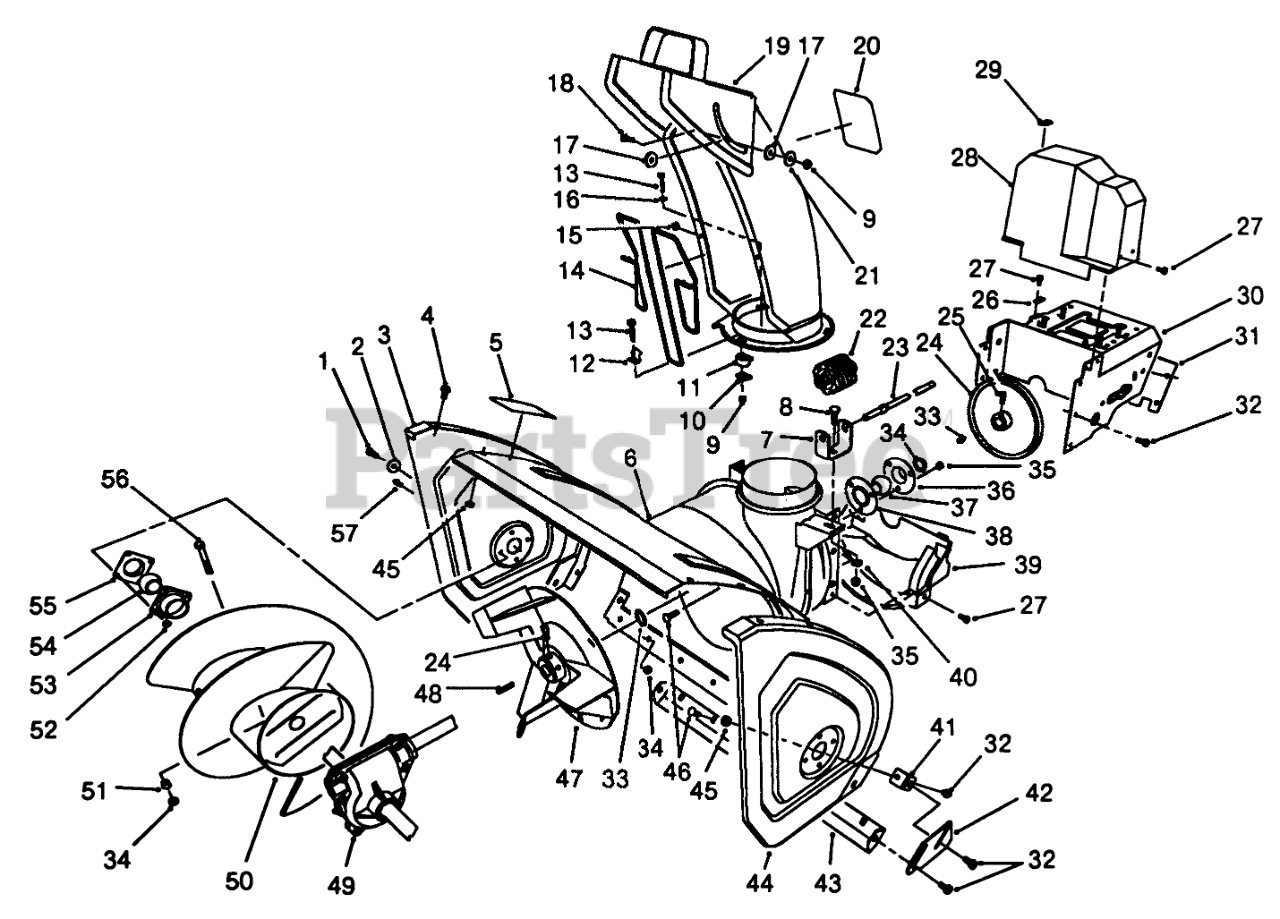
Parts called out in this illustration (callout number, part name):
1	SCREW-HH
2	WASHER
3	R/H SIDEPLATE R
4	SCREW-HHF
5	DECAL-WARNING, AUGER
6	Housing-24 Inch
7	BRACKET-WORM, CHUTE
8	BOLT-CARR
9	NUT-LOCK, NI
10	PLATE-RETAINER, CHUTE
11	RETAINER-CHUTE
12	CLIP-GUARD, CHUTE
13	SCREW-HSH
14	GUARD-CHUTE
15	NUT-PUSH
16	WASHER-FLAT
17	WASHER-PLASTIC
19	Assembly
20	Decal-Danger
21	WASHER-FLAT
22	GEAR-WORM
23	ROD-CHUTE, LOWER
24	PULLEY-IMPELLER
25	SCREW-SET, SQH
26	RETAINER-CABLE
27	SCREW-HWH
28	COVER-BELT, UPPER
29	COVER-CABLE
30	Frame-Engine
31	Cover-Frame, Engine
32	SCREW-HHF
33	KEY-WOODRUFF
34	WASHER-THRUST
35	NUT-LOCK, NI
36	FLANGE-CUP, BEARING
37	BEARING-BALL
38	FLANGE-CUP, BEARING
39	Cover-Belt (Lower)
40	WASHER-PLAIN
41	Bracket-Skid
42	Plate-Skid LH
43	Blade-Scraper
44	L/H SIDEPLATE R
45	NUT-LOCK, NI
46	SCREW-CARR
47	IMPELLER (3) BLD WA BO
49	Auger Gearbox Assembly
50	Auger-RH
51	SPACER-HUB, AUGER
52	NUT-LOCK, CONE
53	BEARING-FLANGE, FRONT
54	BEARING
55	BEARING-FLANGE, REAR
56	Auger Bolt
57	SCREW-HH
